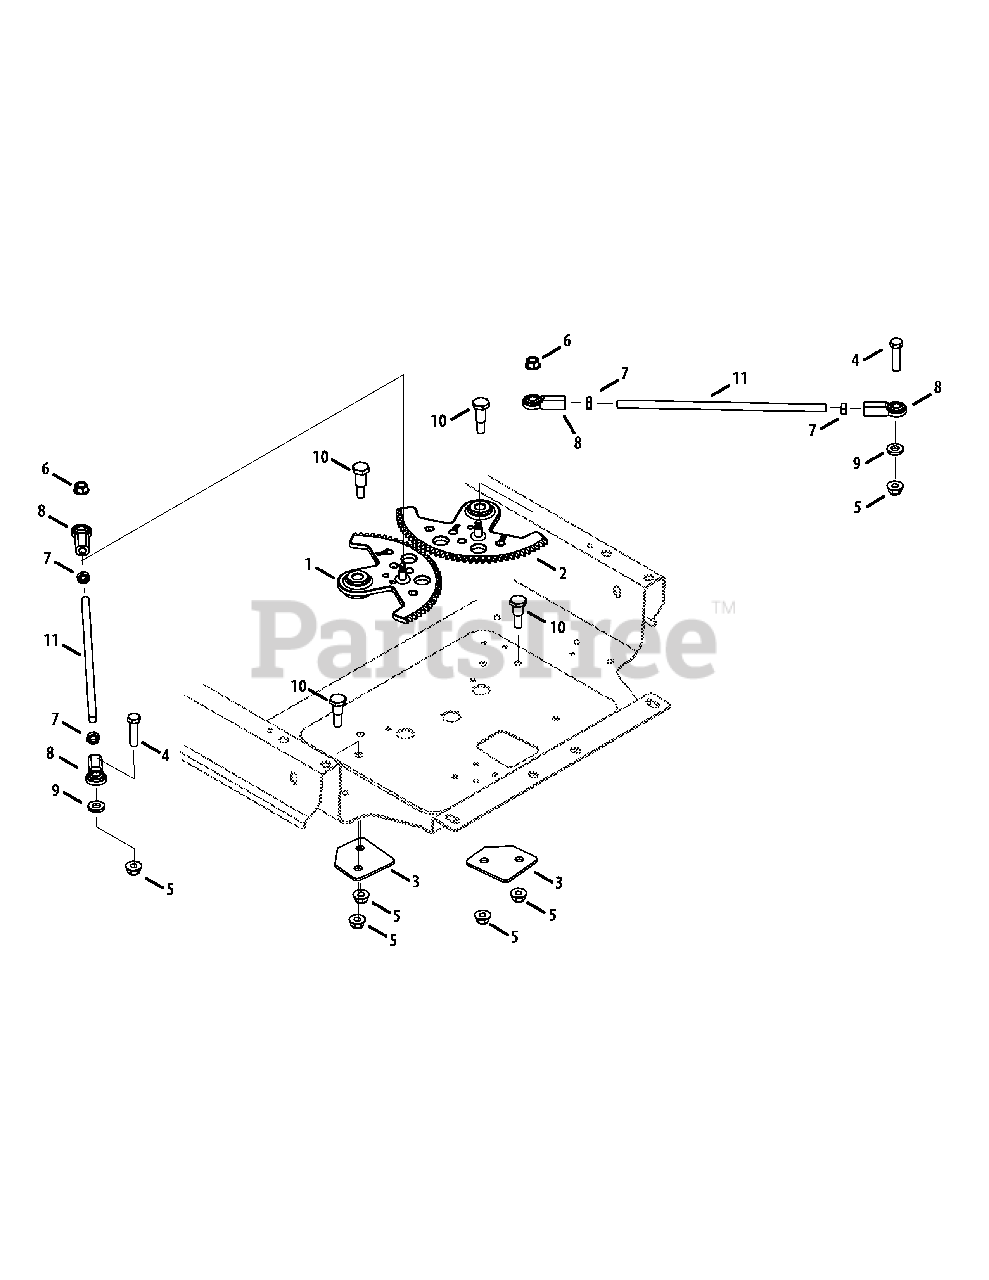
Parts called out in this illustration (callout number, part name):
1	Steering Gear Assembly, RH
2	Steering Gear Assembly, LH
3	Steering Support Plate
4	Hex Screw, 3/8-16 x 1.50
5	Flange Lock Nut, 3/8-16
6	Nut, 5/16-18, Centerlock
7	Jam Nut, 3/8-24
8	Female Ball-Joint
9	Flat Washer, .407 x .812 x .135
10	Shoulder Screw, 3/8-16 x .625 x .875
11	Drag Link, .375 Dia.
